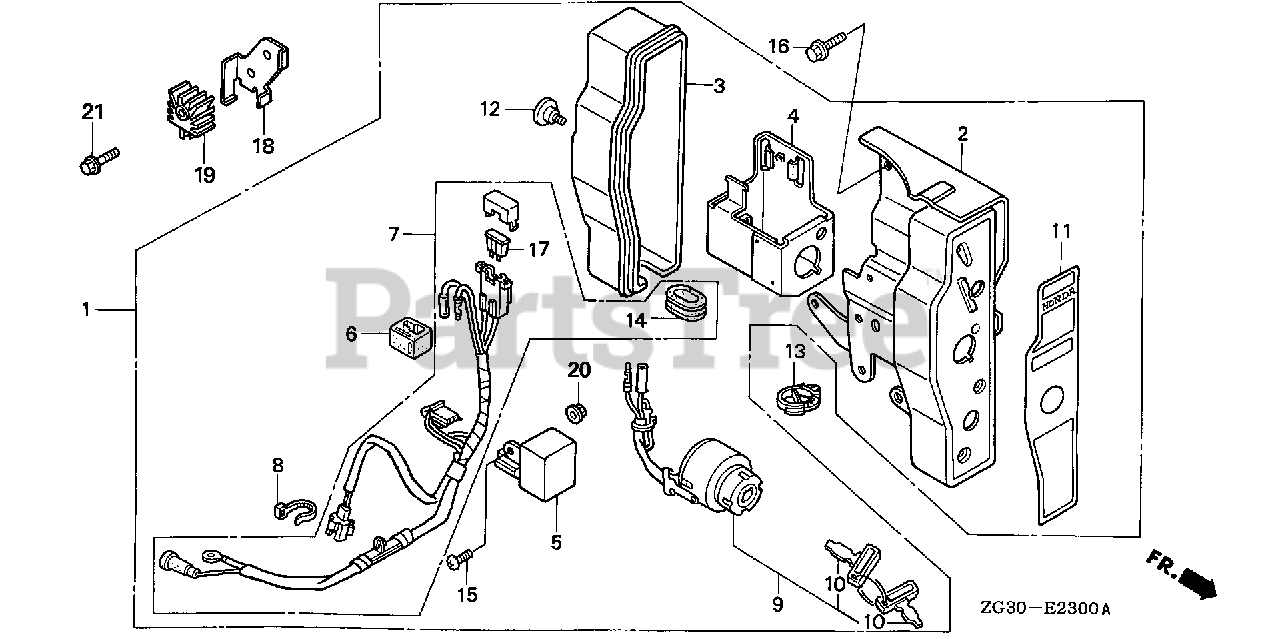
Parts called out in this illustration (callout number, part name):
1	BOX ASSY., CONTROL *NH116M* (URBAN SILVER METALLIC)
2	PANEL, CONTROL *NH116M* (URBAN SILVER METALLIC)
3	CASE, CONTROL
4	BRACKET, CASE MOUNTING
5	RECTIFIER, SILICON
6	SUSPENSION, CONNECTOR
7	WIRE HARNESS ASSY., CONTROL
9	SWITCH ASSY., COMBINATION
10	KEY (HONDALOCK)
11	MARK, CONTROL BOX (EXTERNAL)
12	SCREW, SPECIAL (6X12)
13	CLIP, HARNESS
14	GROMMET, WIRE HARNESS (NOT AVAILABLE)
15	SCREW, PAN (6X12)
16	BOLT, FLANGE (6X16)
17	FUSE, BLADE (15A)
